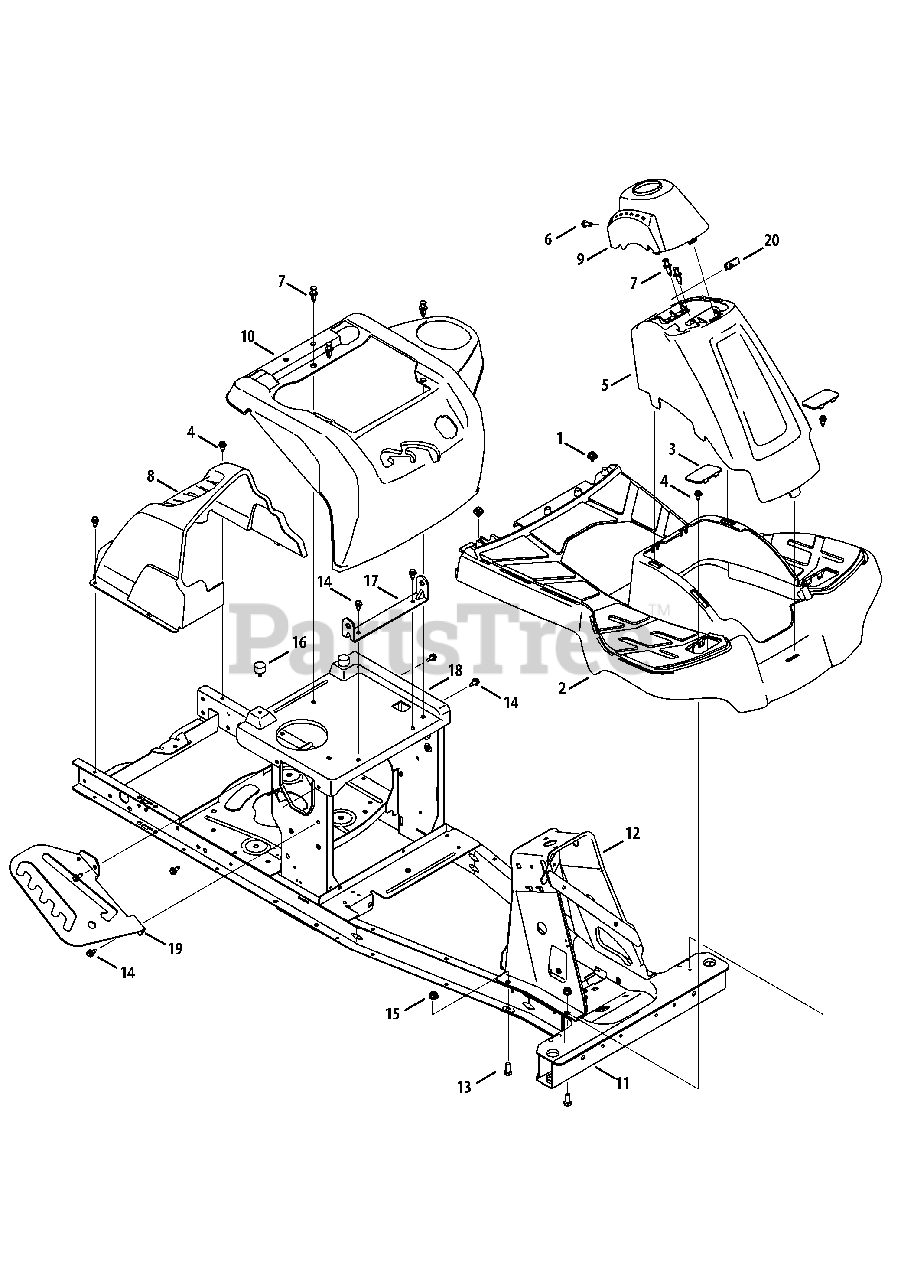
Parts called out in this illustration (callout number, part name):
1	Screw, 1/4-20 x .500
2	Running Board
3	Running Board Plug
4	Shoulder Screw, .368 X.113: 1/4-20
5	Column Cover
6	Machine Screw, 1/4-20, 0.750
7	Rivet, .3125
8	Drive Cover
9	Steering Column Cap
10	Fender
11	Frame Assembly
12	Column Assembly
13	Hex Washer Screw, 5/16-18 x .875
14	Tap Screw, 1/4-20, .625
15	Flange Locknut, 5/16-18
16	Bumper, .62 Dia. x .50
17	Seat Pivot Bracket
18	Seat Plate
19	Deck Lift Index Bracket
20	U-type Speed Nut, 1/4-20
